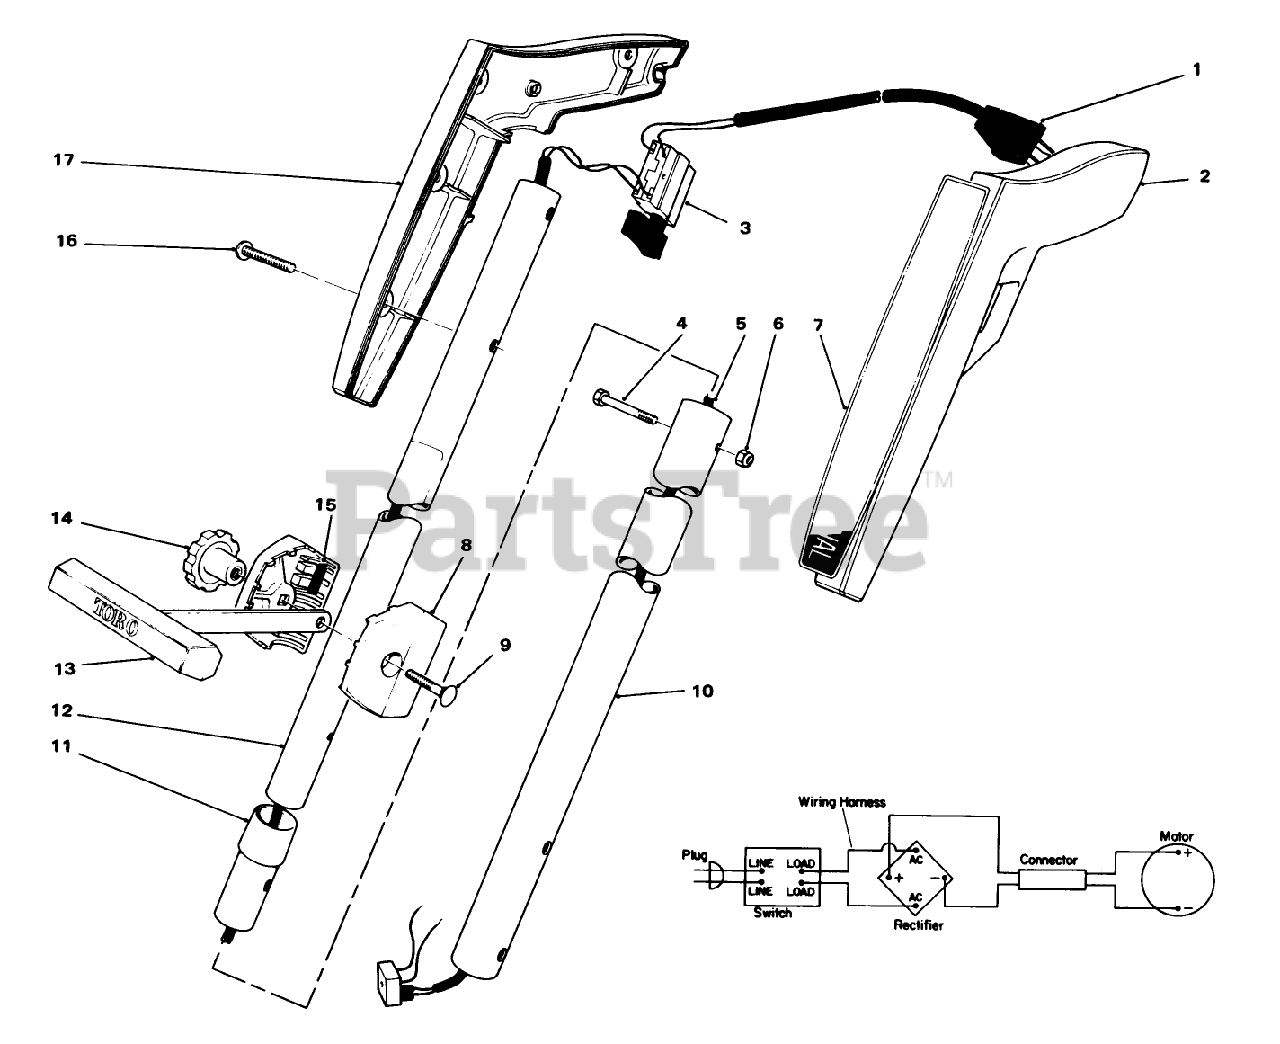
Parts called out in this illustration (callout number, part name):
1	Power Cord
2	Left Hand Grip
3	Two Speed Switch
4	Screw
5	WIRE HARNESS
6	NUT-LOCK, NI
7	Decal
8	Bracket
9	BOLT-CARR
10	Lower Tube
11	Tubing Sleeve
12	Tube-Upper
13	Tee Handle
15	RUBBER INSERT
16	Screw
17	Right Hand Grip
